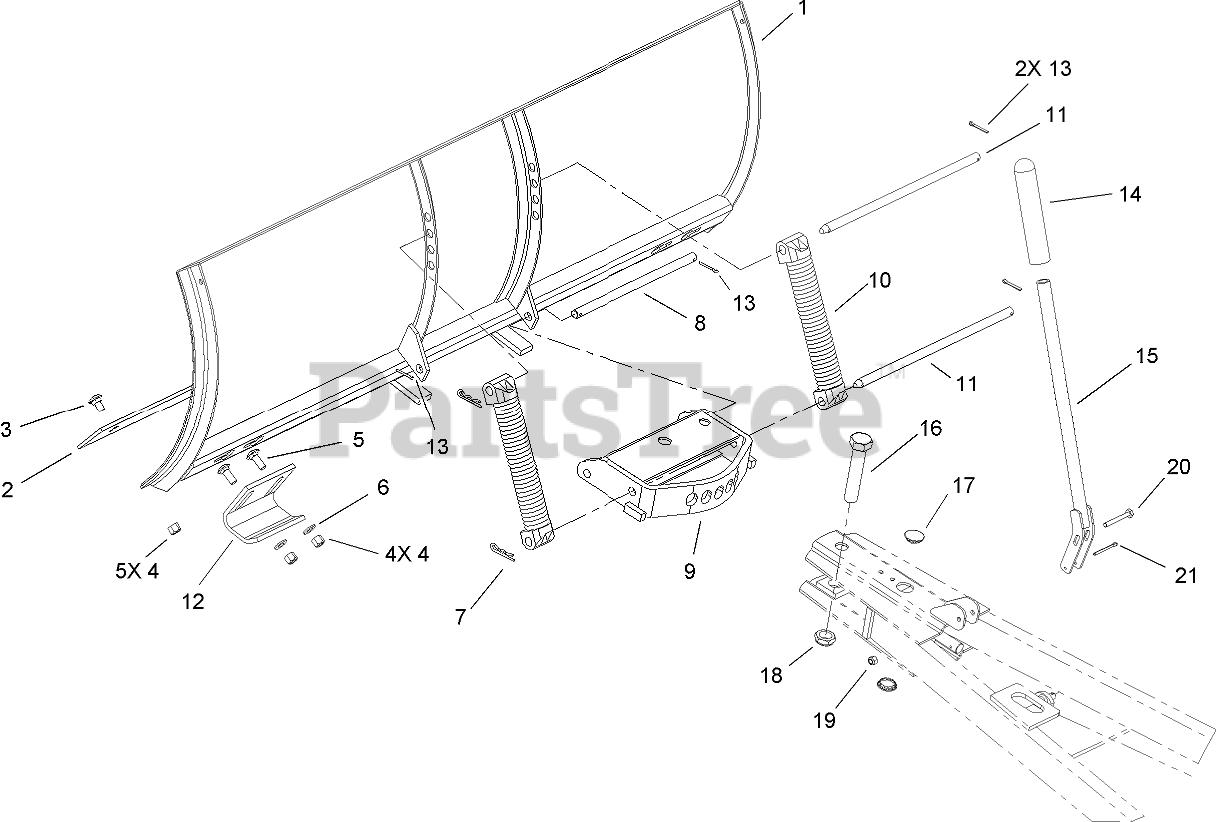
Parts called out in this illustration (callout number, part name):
2	PLATE-EDGE, BLADE
3	SCREW-CARR
4	NUT-LOCK, NI
5	BOLT-CARR
6	WASHER-FLAT
7	PIN-HAIR
8	ROD-LOWER
9	QUADRANT
10	LUG / SPRING ASM
11	ROD-PIVOT, BLADE
13	PIN-COTTER
14	GRIP-HANDLE
15	LEVER-INDEX
16	SCREW-HH
17	PLUG
18	NUT-LOCK
19	NUT-LOCK, NI
20	SCREW-HH
21	PIN-COTTER
